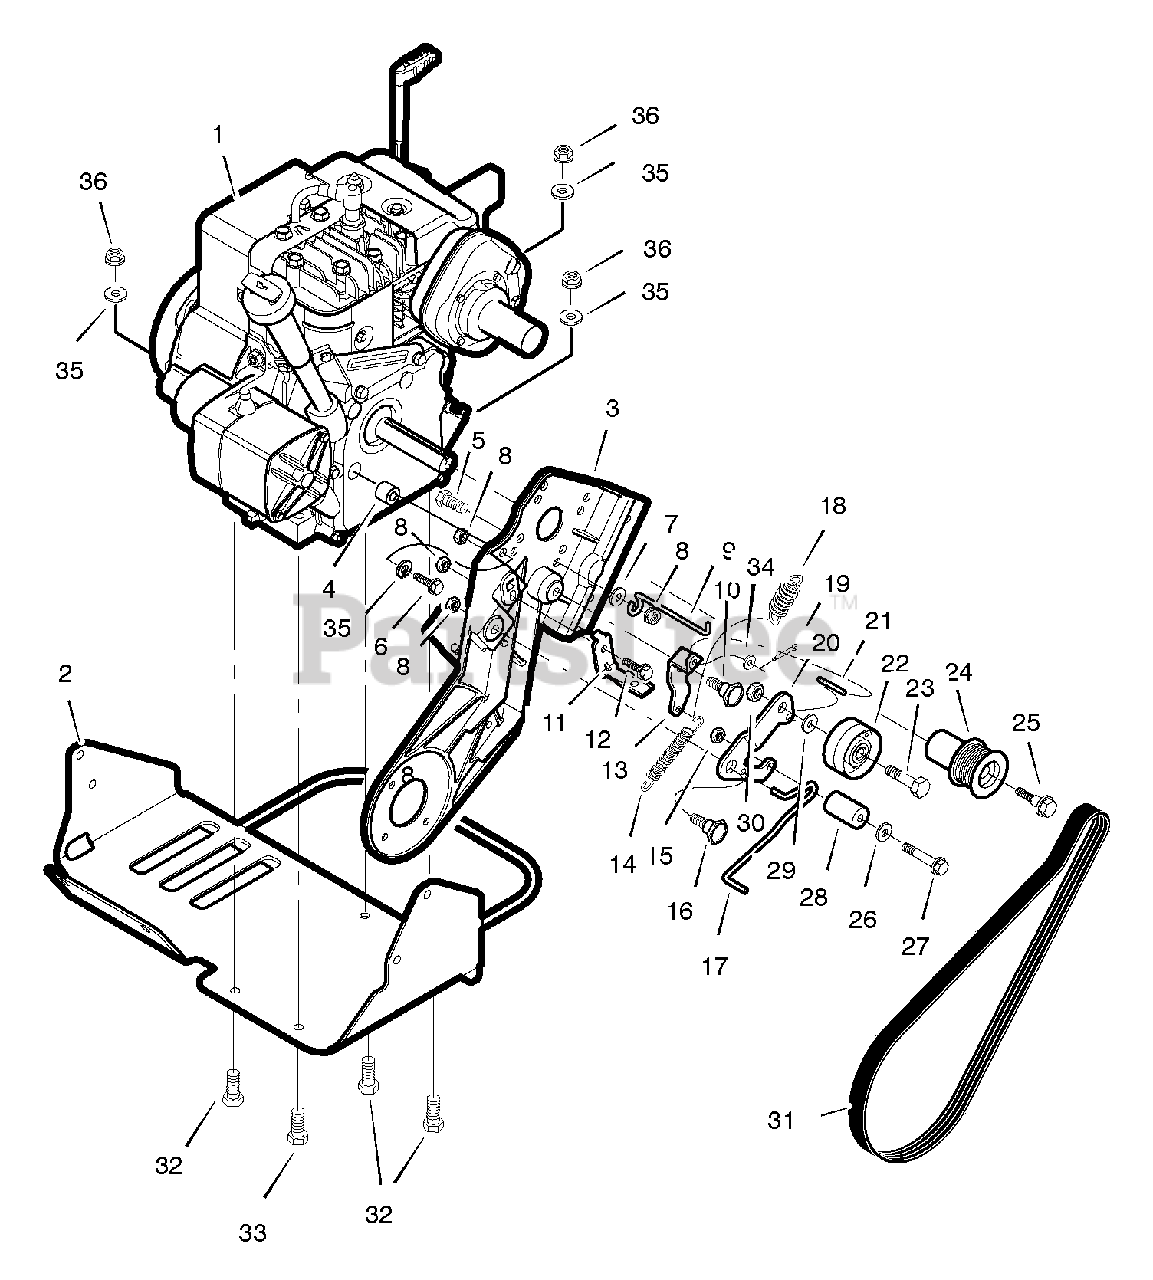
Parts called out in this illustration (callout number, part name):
1	Engine
2	Cradle Assy, Engine
3	Frame, Left
4	Mount, Antivibration
5	Bolt 5/16-18x 0865
6	Bolt 5/16-24x1.125
7	Washer, Flat
8	Locknut 5/16-18
9	Guide, Belt
11	Pad, Brake
12	Screw, 1/4-20 x .63
13	Idler, Arm Pivot
15	Nut Hex 1/4-20
17	Wire, Brake
19	Pin, Cotter
20	Arm, Idler
21	Rod, Clutch Linkage
22	Pulley, Idler
23	Screw, 3/8-16 x 1.50
24	Pulley, Engine
25	Bolt, Engine Pulley
26	Washer, Flat
27	Screw, 1/4-20 x 2.00
28	Pinch Roller
29	Washer, Flat
30	Nut, Hex
31	Belt, Drive
32	Bolt, Hex 5/16-18X1.625
33	Screw 3/8-16X1.00
34	Washer, Flat
35	Lockwasher, Split
36	Nut 5/16-18
